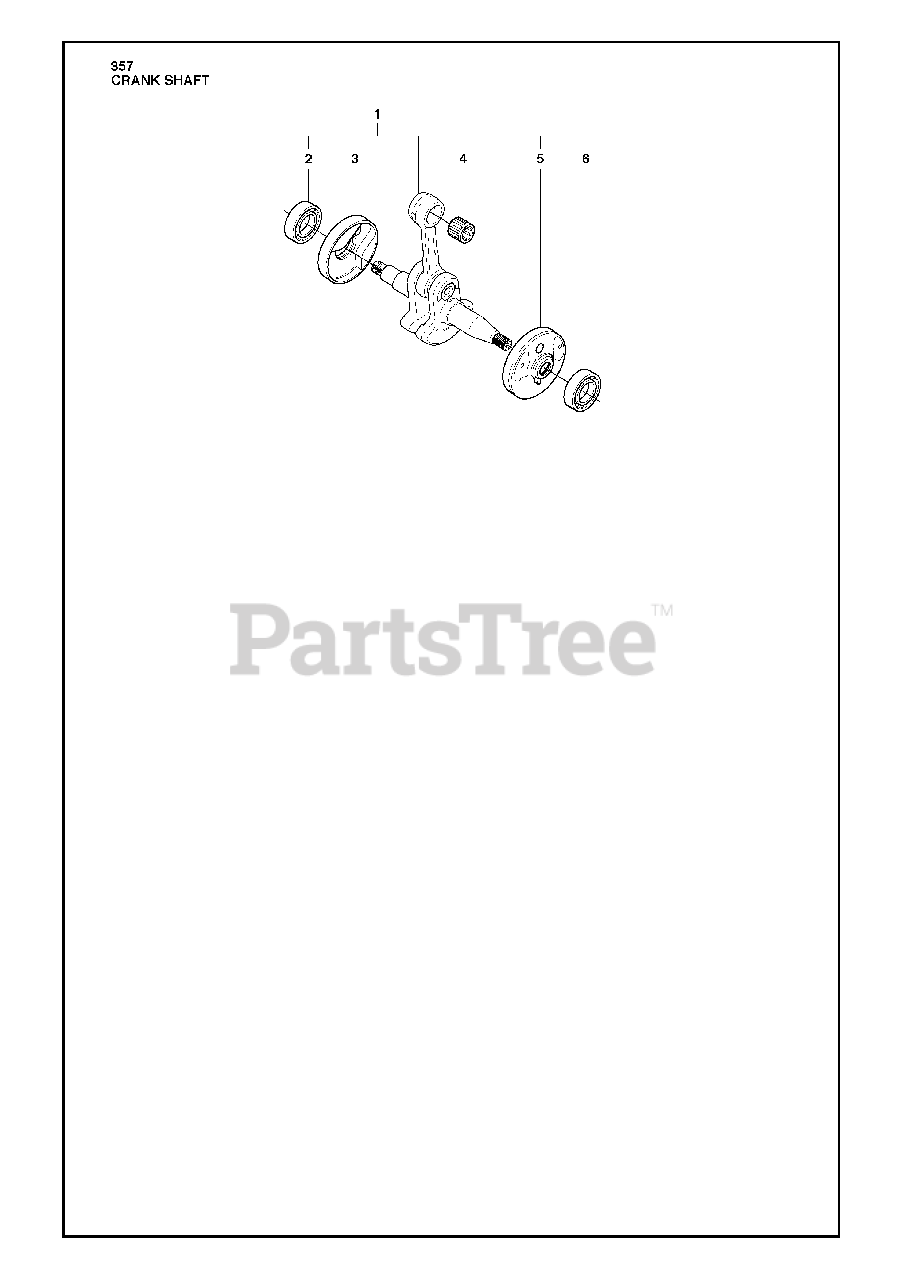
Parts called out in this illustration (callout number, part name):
1	RP CRANKSHAFT ASSY
2	BALL BEARING-6202-C3 SKF
4	SUPPORT BUSHING
6	BALL BEARING-6202-C3 SKF
